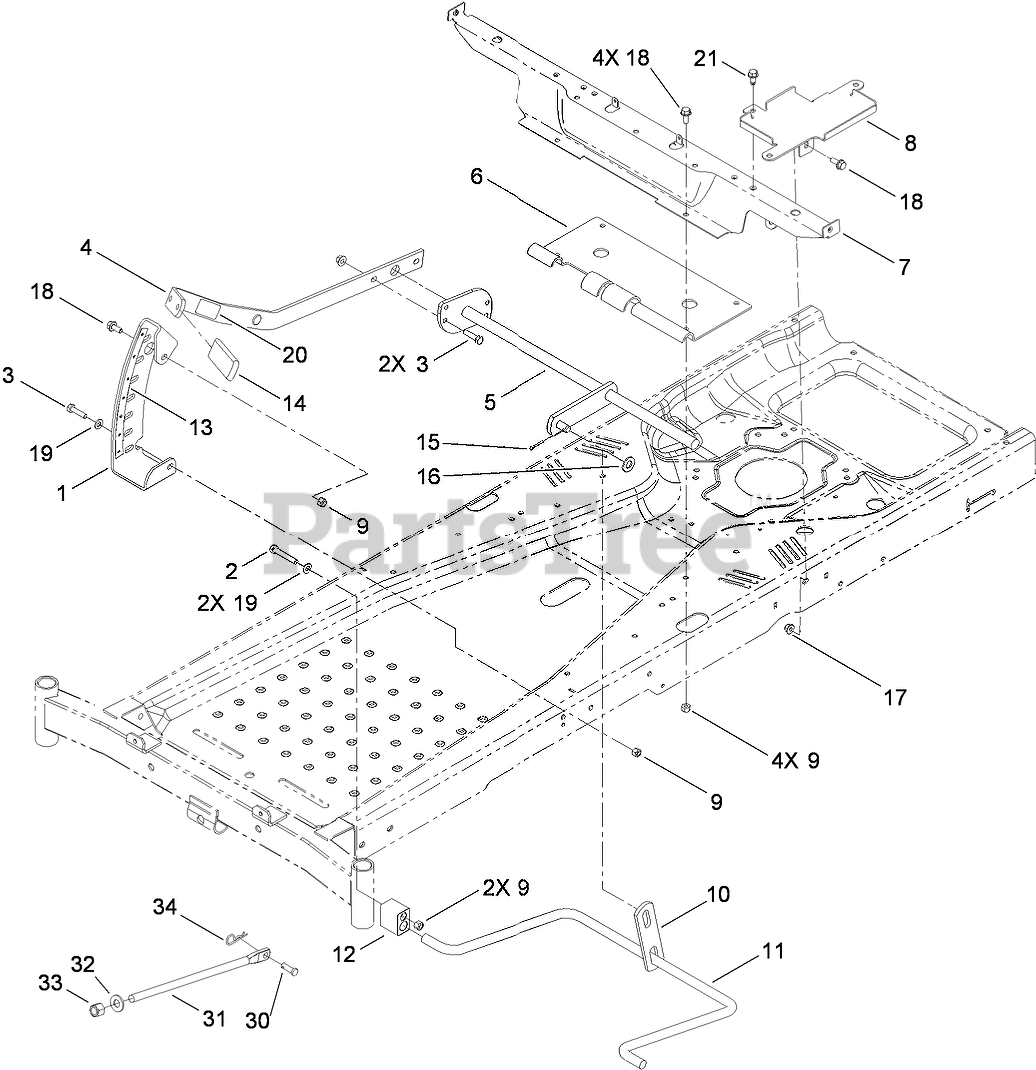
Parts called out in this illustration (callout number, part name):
1	SECTOR-HOC
2	SCREW-HH
3	SCREW-HH
4	LIFT ARM ASM
5	LIFT LEVER ASM
6	PLATE-LIFT
7	BRACKET-SEAT/PODS
8	TRAY-BATTERY
9	NUT-LOCK, NI
10	LINK-LIFT
11	ARM-LIFT, REAR
12	BLOCK-PIVOT
13	DECAL-HOC
14	GRIP-LEVER, LIFT
15	PIN-COTTER
16	WASHER-FLAT
17	NUT-HF, NI
18	SCREW-HHF
19	WASHER-PLAIN
20	DECAL-HOC
21	SCREW-HWH
30	PIN-CLEVIS
31	ROD-LIFT
32	WASHER-THRUST
33	NUT-LOCK, NI
34	PIN-HAIR
